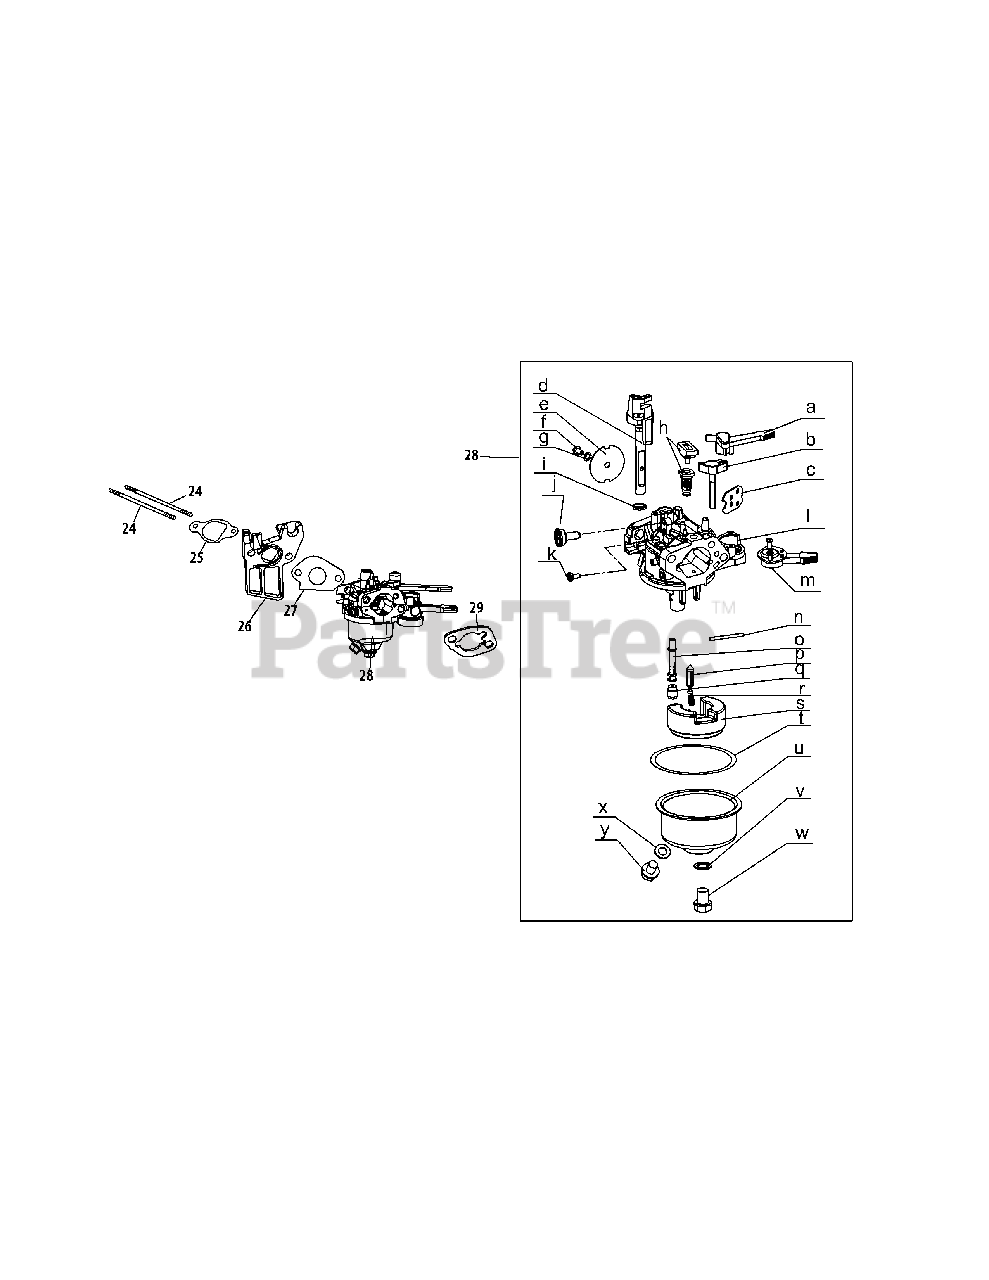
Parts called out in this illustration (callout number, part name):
24	Stud M6×110
25	Carburetor Insulator Gasket
26	Carburetor Insulator
27	Carburetor Gasket
28	Carburetor Assembly
29	Carburetor Gasket Plate
